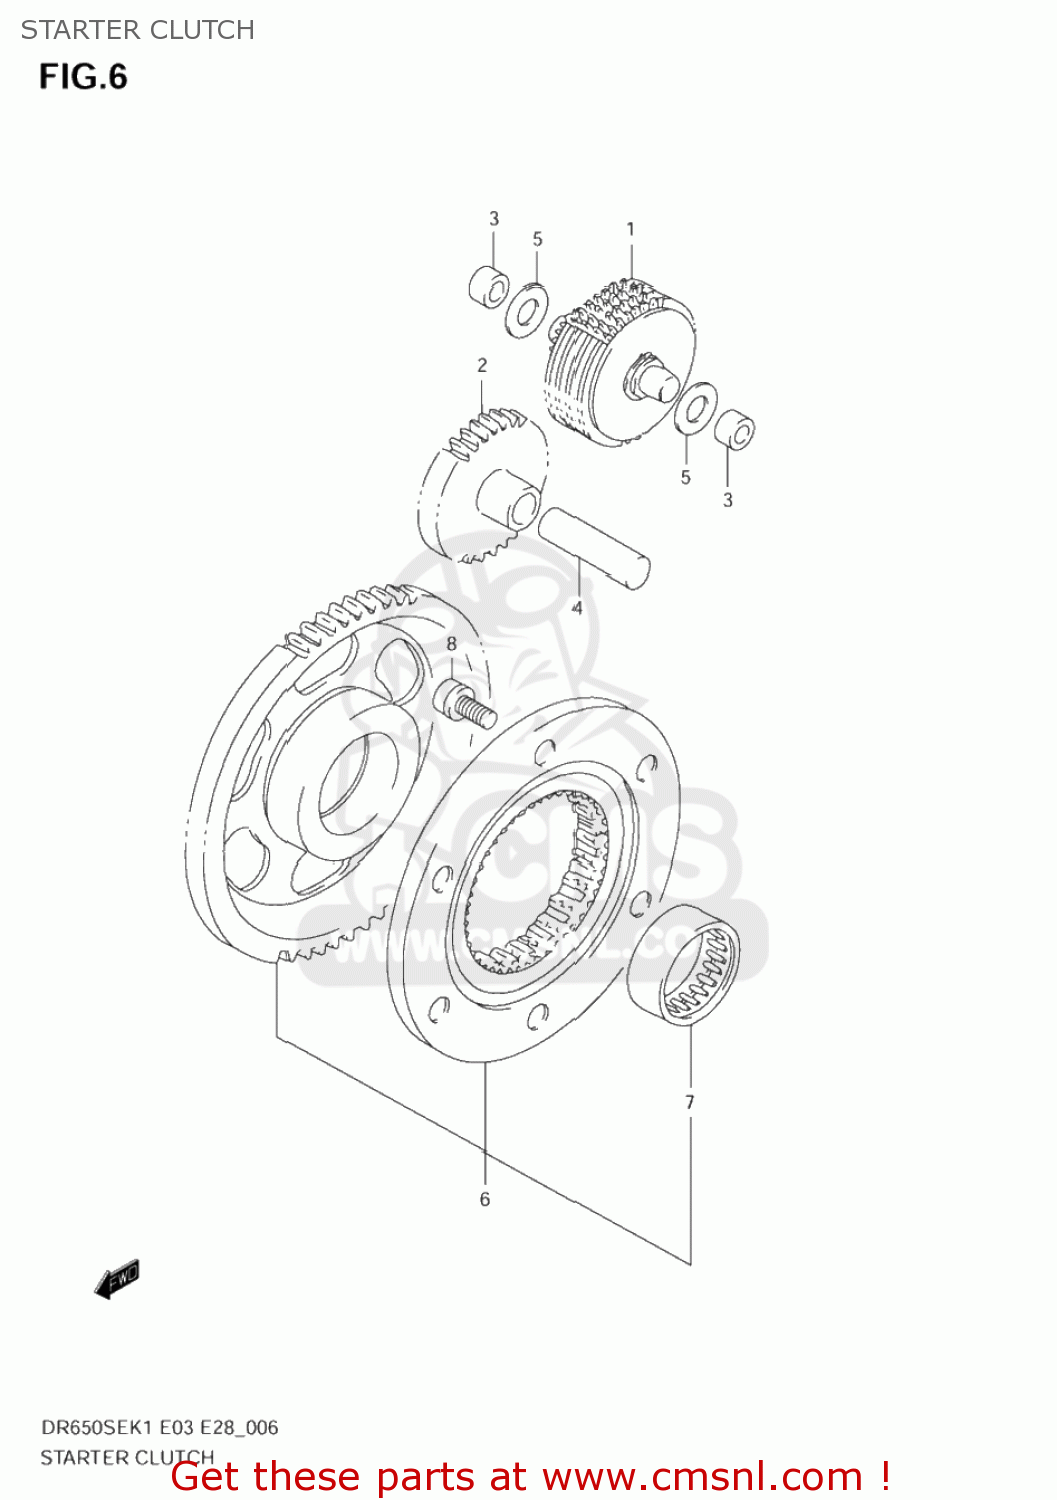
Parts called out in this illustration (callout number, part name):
1	LIMITER ASSEMBLY,STARTER IDLER GEAR
2	GEAR,STARTER IDLE NO.2(NT:27)
3	BUSH,LIMITER GEAR SHAFT
4	PIN
5	WASHER
6	CLUTCH SET,STARTER
7	BEARING(31X39X17.8)
8	BOLT
